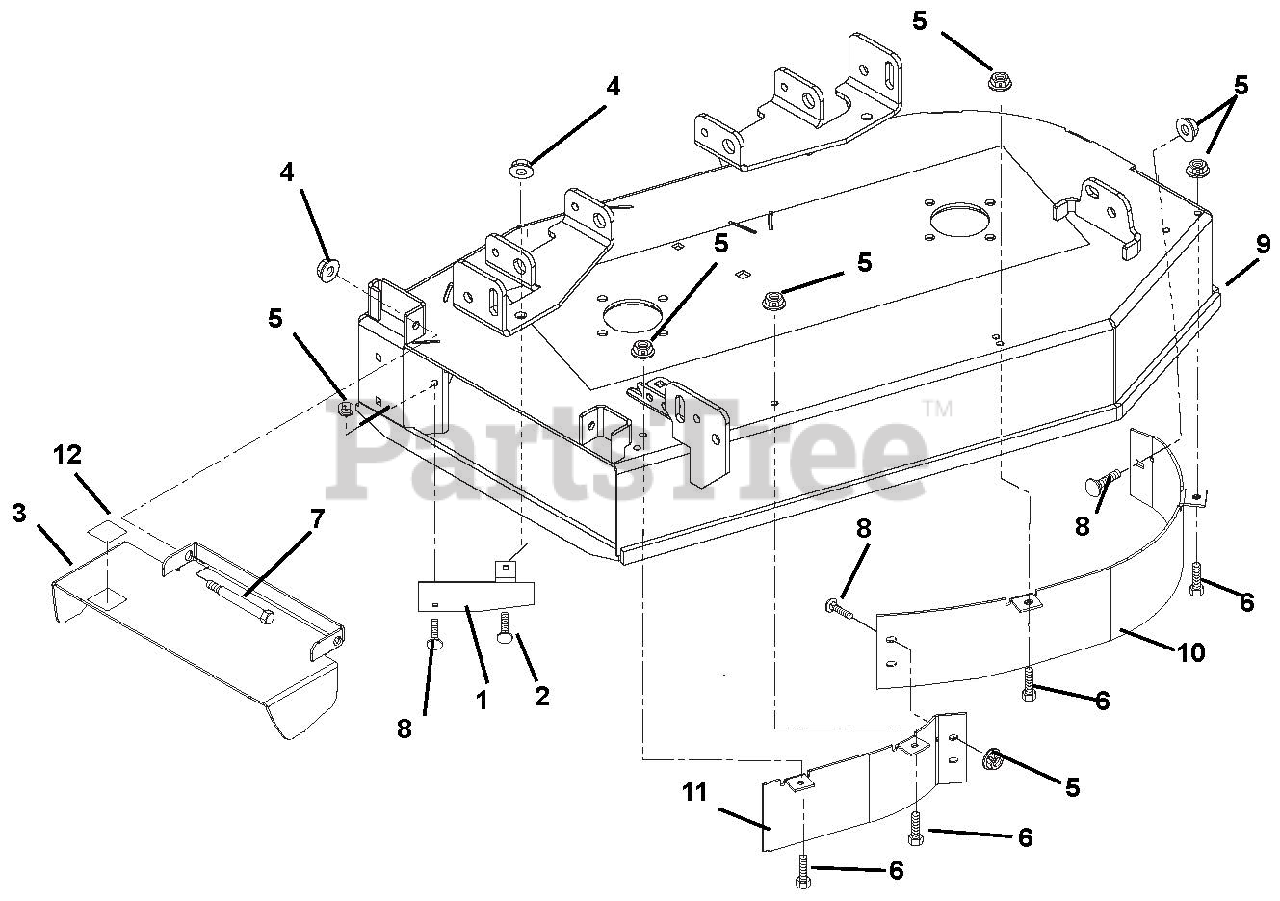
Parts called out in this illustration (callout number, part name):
1	Baffle, Deflector
2	Bolt, Round Head Square Neck .38-16 x 1.25 Grade 5
3	Chute, Discharge
4	Nut, Nyloc Flange 3/8-16
5	Nut, Nyloc Flange 5/8-18
6	Bolt-Hex .31-18 x .75 Grade 5
7	Bolt-Shoulder .38-16 x .50 Socket Head
8	Bolt-Round Head Square Neck .31-18 x .75 Grade 5
9	Weldment, 34" Side Discharge Deck
10	Baffle, 34" Front Left Hand
11	Baffle, 34" Front Right Hand
12	Grip, Pedal 1.50 x 3.00
